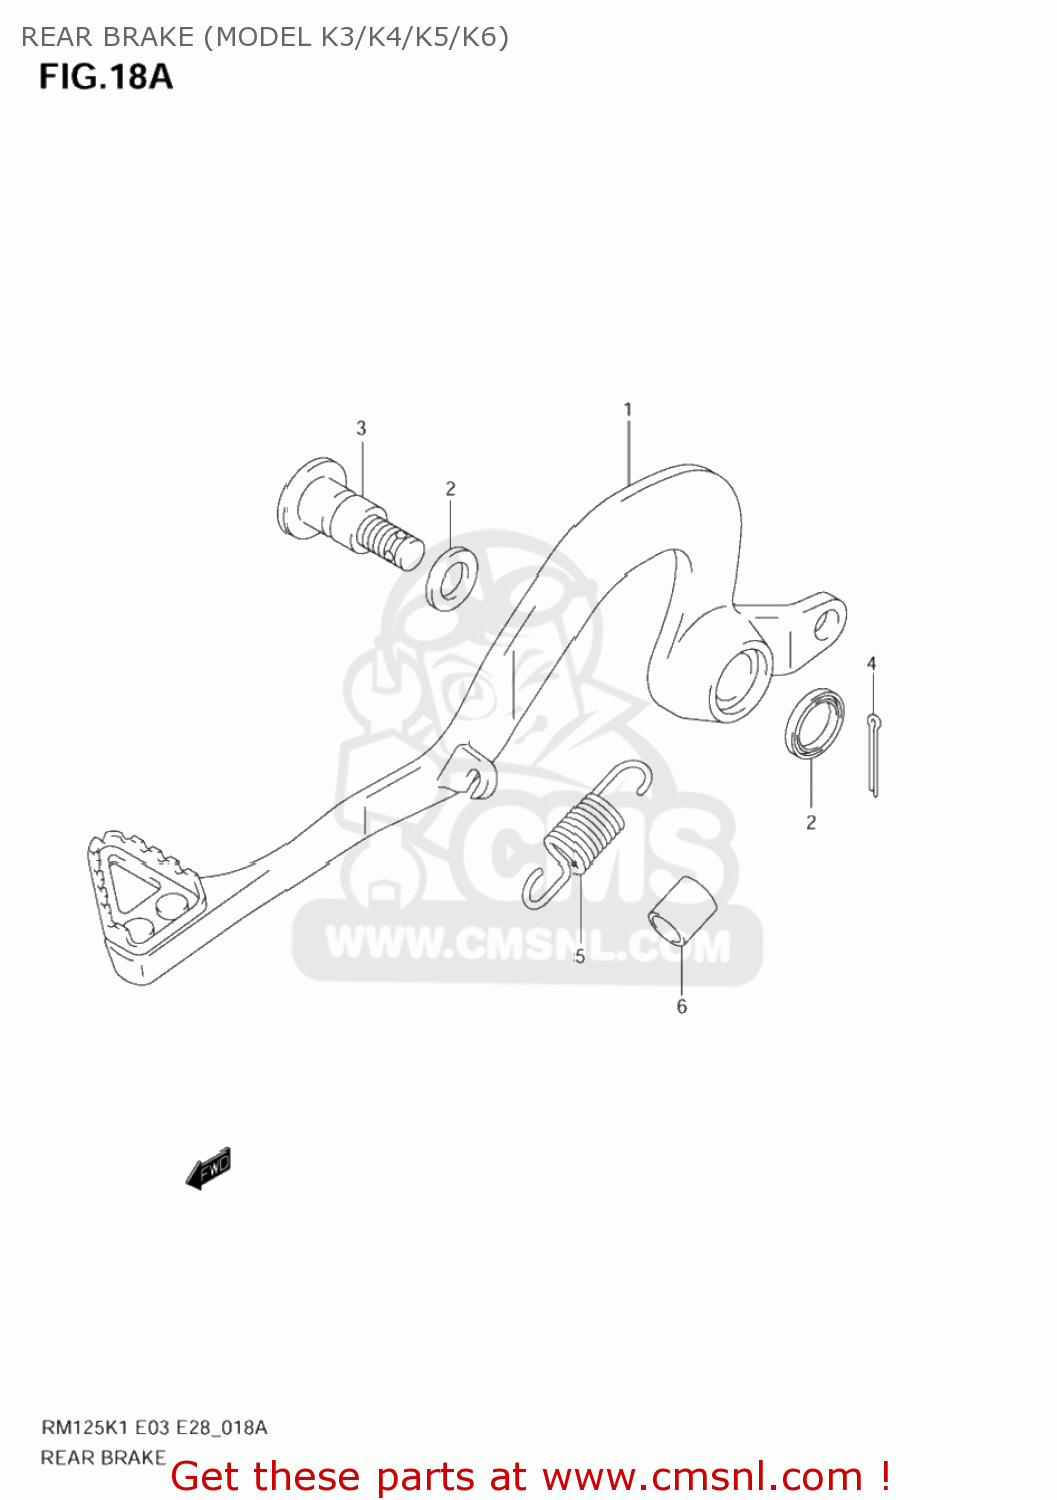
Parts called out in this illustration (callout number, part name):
1	PEDAL ASSY,BRAKE
2	SEAL,OIL(15X21X3)
3	SHAFT,BRAKE PEDAL
4	PIN 20X20
5	SPRING
